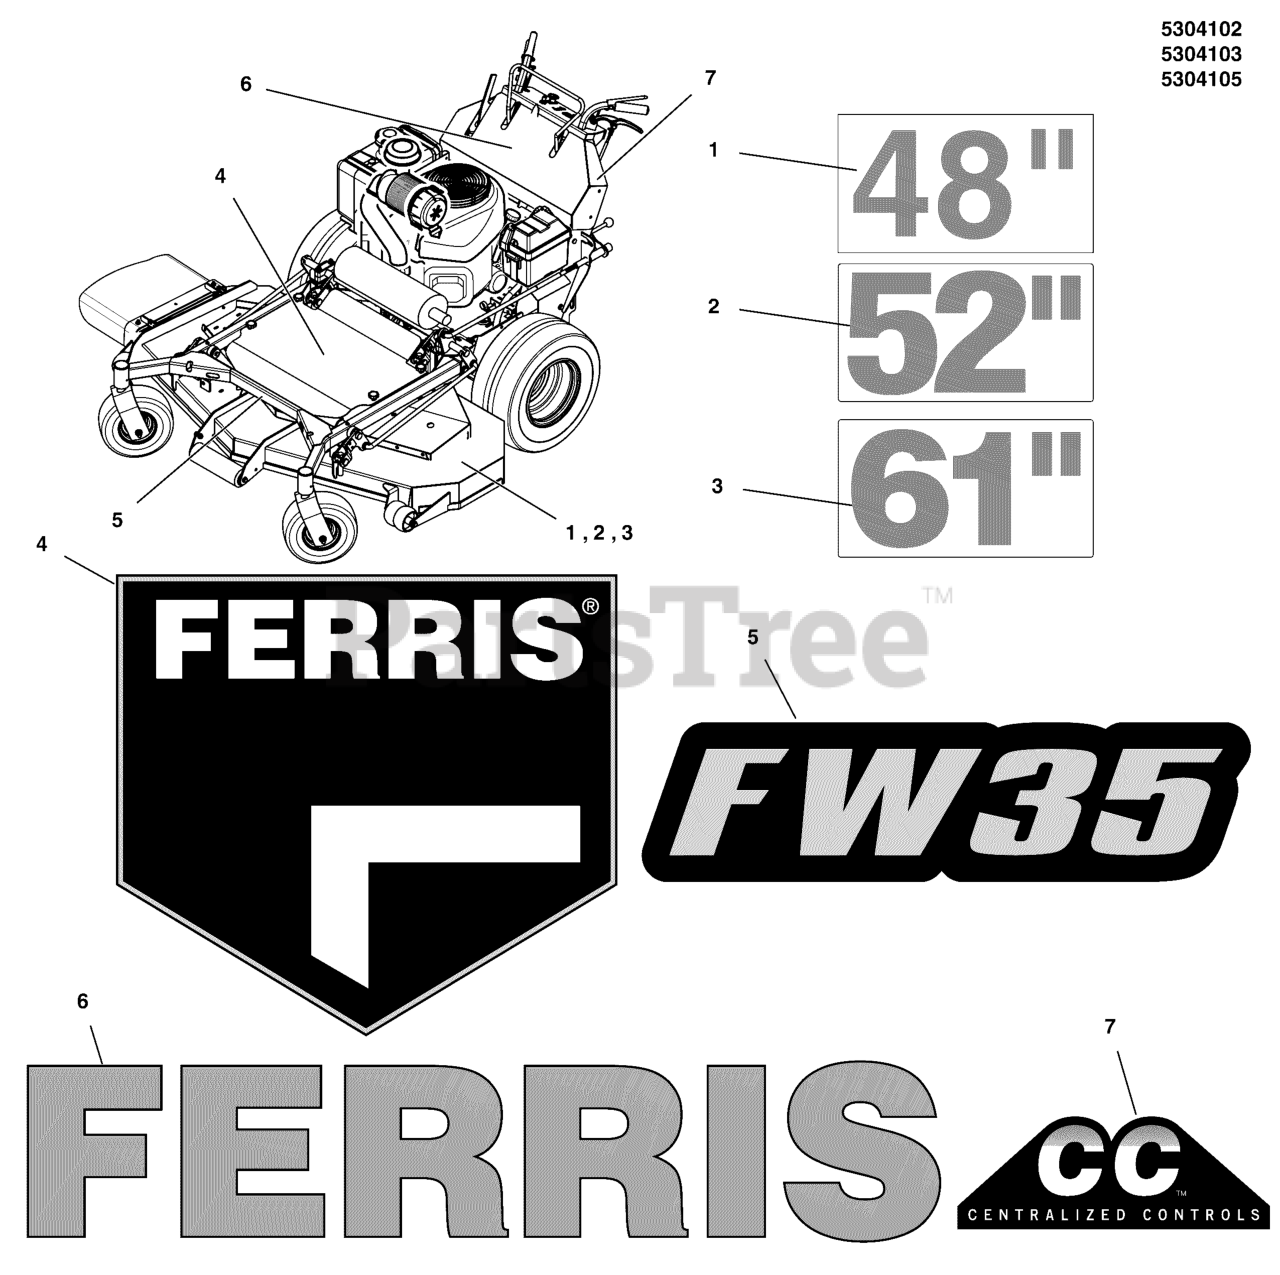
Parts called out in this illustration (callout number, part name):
1	DECAL, 48
2	DECAL, 52
3	DECAL, 61
4	DECAL, BRAND
5	DECAL, MODEL
6	DECAL, FERRIS, 2.23" X 11.39"
7	DECAL, CENTRALIZED CONTROLS
